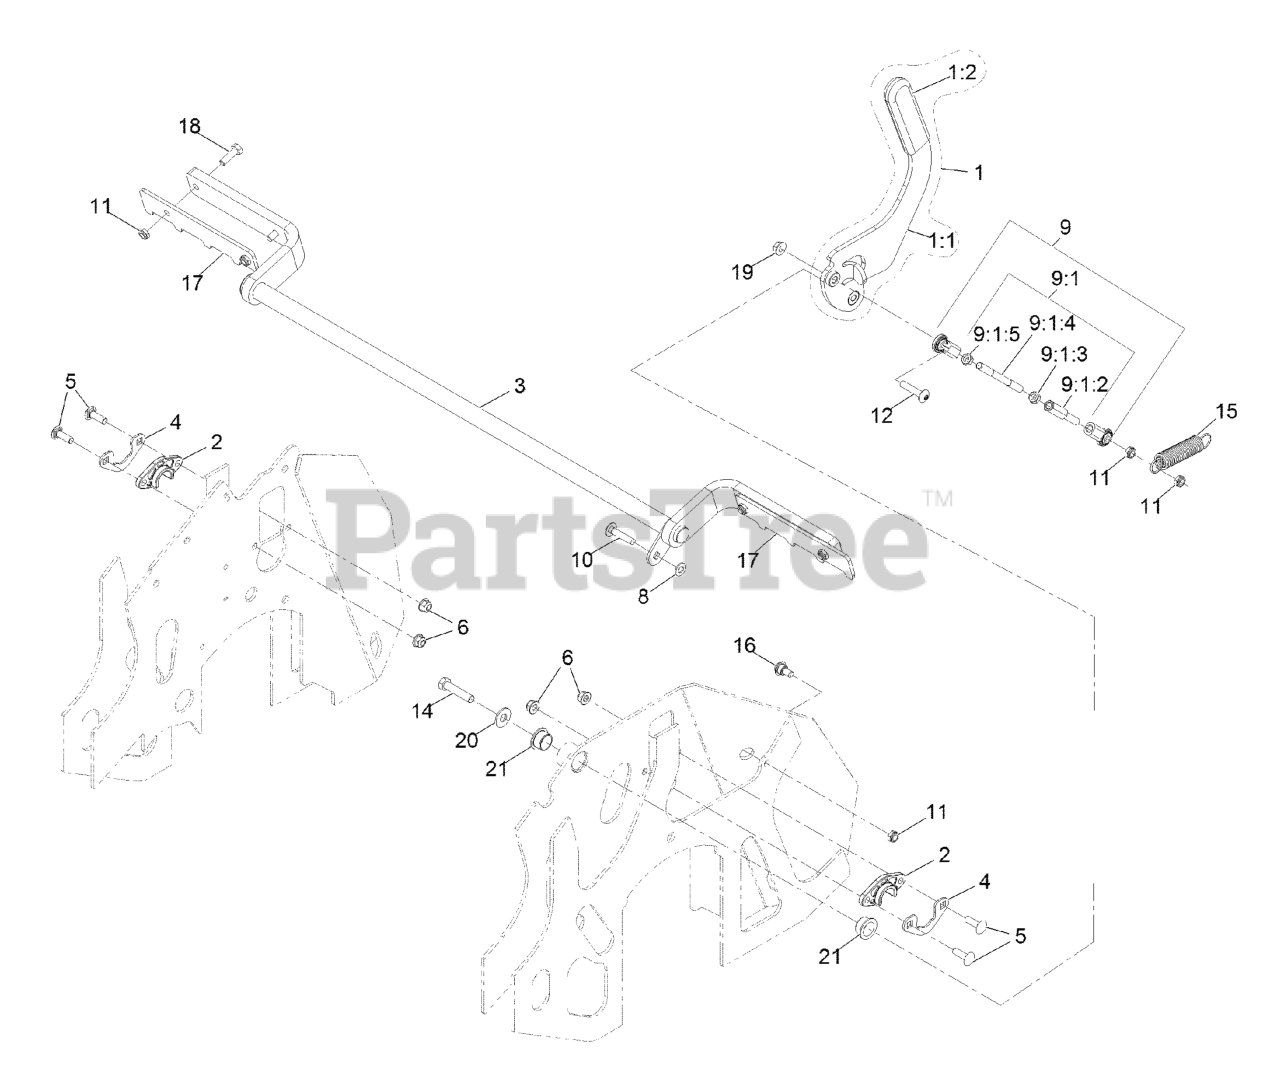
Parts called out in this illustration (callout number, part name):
1	ASM, Brake Lever W/ Grip
1:1	Weld, Brake Lever
1:2	GRIP-LEVER
2	BUSHING-FLANGE
3	Weld, Brake Shaft
4	SUPPORT, BEARING
5	SCREW-CARR
6	NUT-HF, NI
8	WASHER-PLAIN
9	ASM, Linkage
9:1	ASM, Motion Control Link
9:1:2	ROD-ADJUSTMENT
9:1:3	NUT-HEX JAM, LH
9:1:4	Link, Motion Control
9:1:5	NUT-HJ
10	BOLT-CARR
11	NUT-LOCK, NI
12	SCREW-TORX
14	SCREW-HH
15	SPRING-IDLER
16	BOLT-SHOULDER
17	Plate, Snubber
18	SCREW-HH
20	WASHER-FLAT
21	Bushing, Igus
